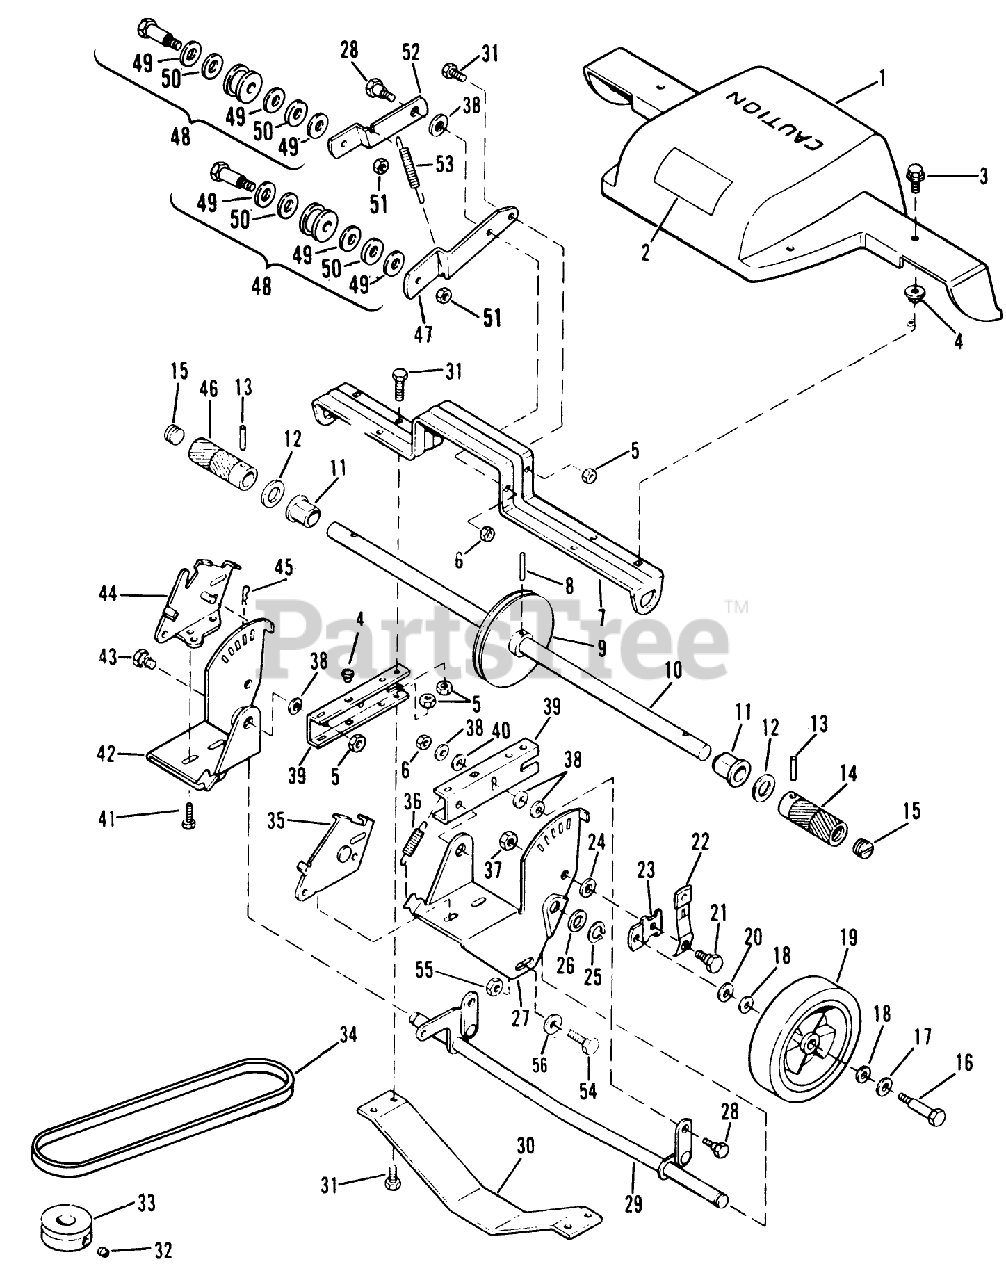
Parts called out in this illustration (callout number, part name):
1	COVER & DECAL AY
5	LOCKNUT E
6	STOP NUT
8	ROLL PIN
11	SLEEVE &BEARING AY
15	GREASE PLUG
16	BOLT WHEEL
20	WASHER WROUGHT
22	KNOB&SPRING FORMCO
25	RET RING
28	BOLT RB&W
32	SET SCREW F
33	PULLEY F
37	LOCKNUT
38	WASHER S
43	BOLT RB&W
45	HAIR PIN
46	R.H. DRIVE ROLLER
47	DISCOUNTED
49	THRUST WASHER
51	NUT-LOCK F
55	NUT-LOCK F
